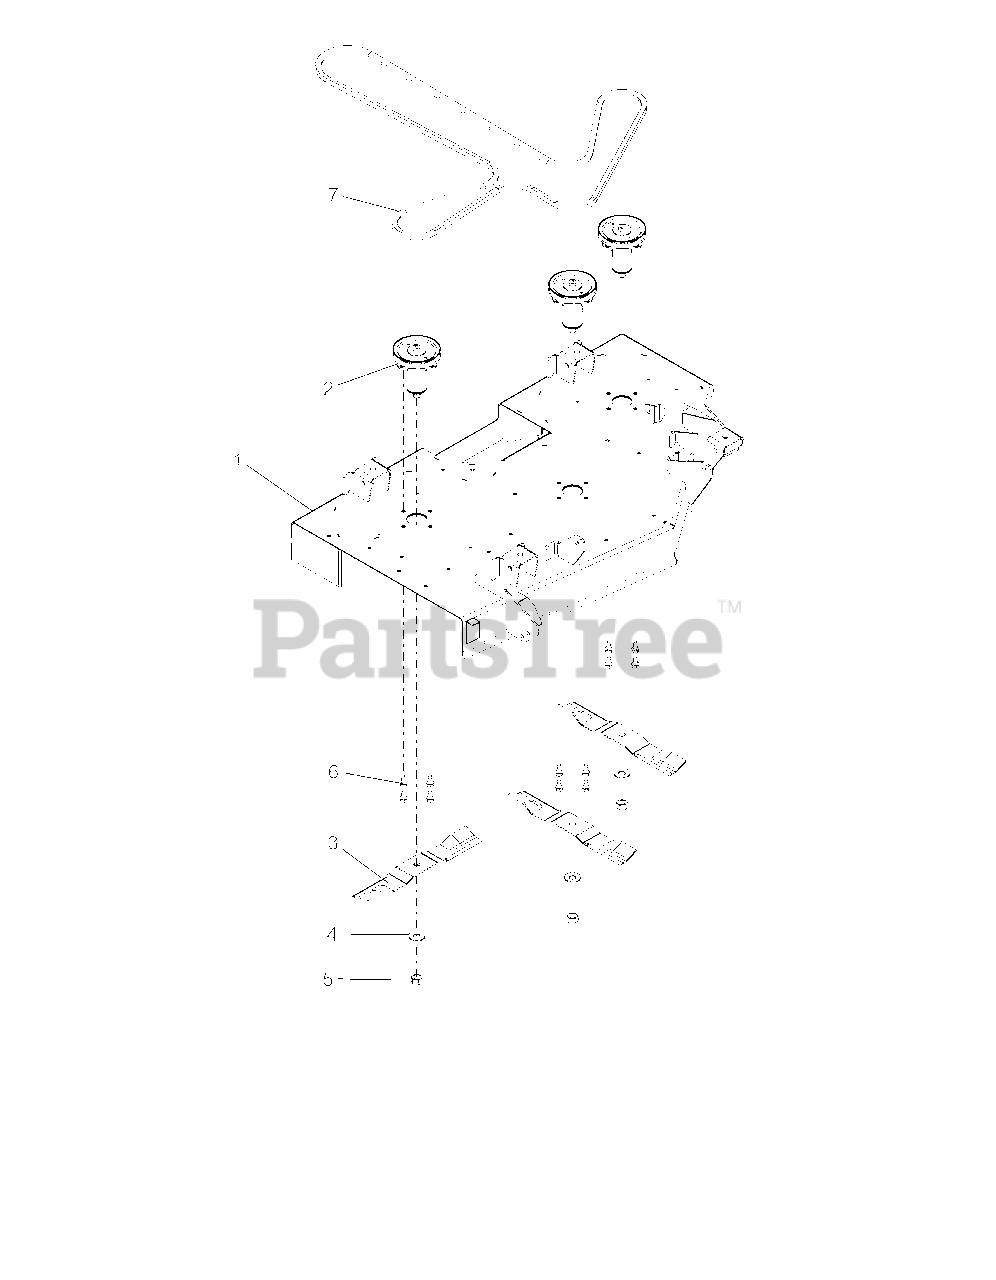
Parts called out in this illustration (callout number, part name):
1	KIT, 42" GRAVELY DECK W/DECALS
2	KIT, DECK SPINDLE ASM-IKON-ZTX
3	BLADE, MOWER 15.00"
4	WSHR-BLVL .669X1.535X.138
5	NUT-STD .625-18 ZCC
6	SCR,TAP .375-16X.75 HWH TR ZCC
7	V-BELT, 4L-WRAPPED
